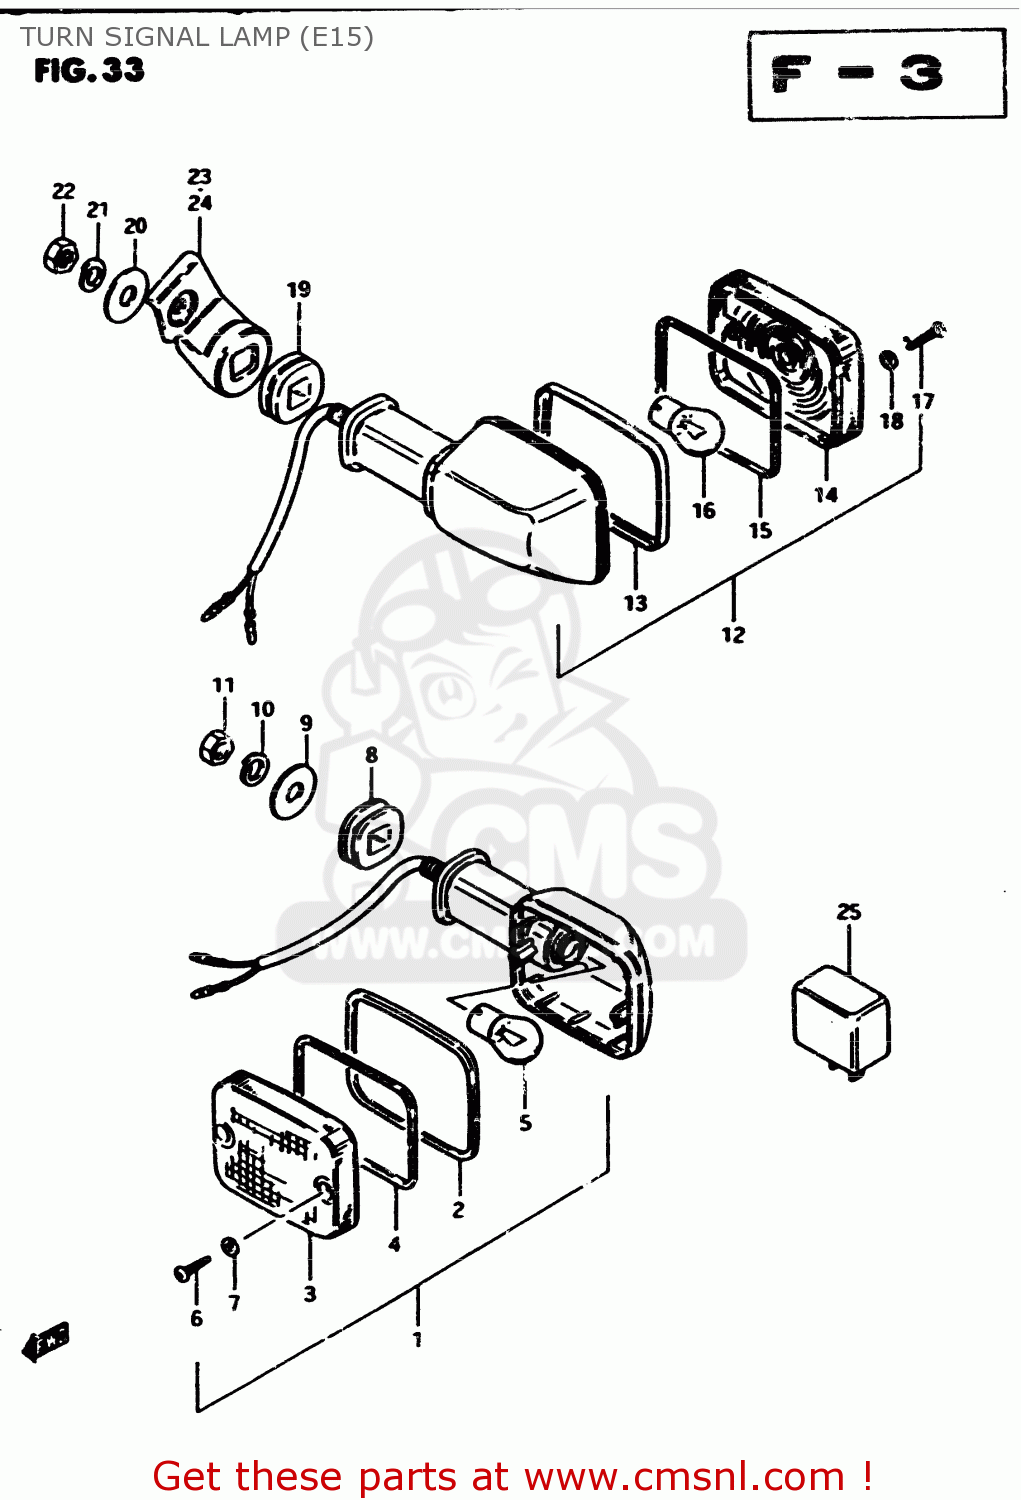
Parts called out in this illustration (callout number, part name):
1	LAMP ASSY,FR T
2	RIM
3	LENS
4	GASKET (NAS)
5	BULB(12V21W)
6	SCREW
7	GASKET (NAS)
8	CUSHION
9	WASHER (10.5X30X2.3)
10	LOCK WASHER
11	NUT
12	LAMP ASSY,RR T
13	RIM
14	LENS
15	GASKET (NAS)
16	BULB(12V21W)
17	SCREW
18	GASKET (NAS)
19	CUSHION
20	WASHER (10.5X30X2.3)
21	LOCK WASHER
22	NUT
23	BRACKET,REAR TURN SIGNAL
24	BRACKET,REAR TURN SIGNAL
25	RELAY,TURN SIGNAL
